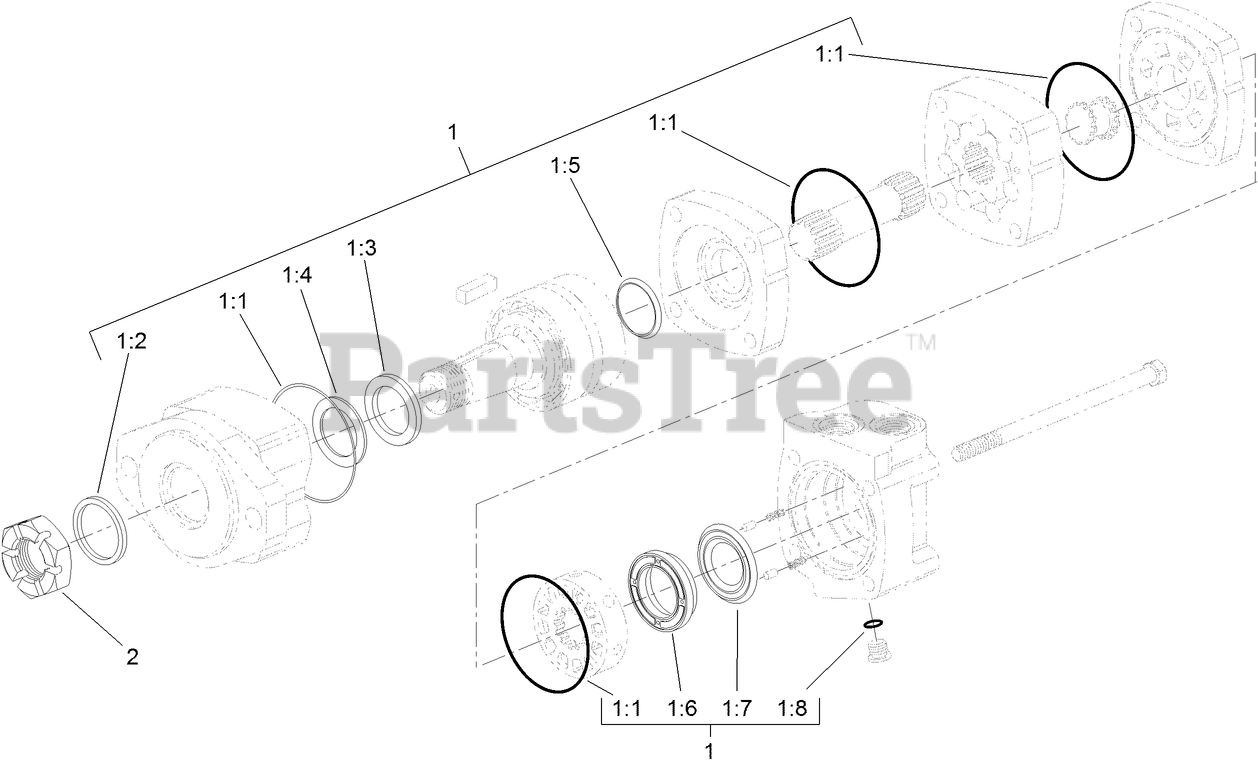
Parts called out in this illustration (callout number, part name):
1	SEAL KIT
1:1	SEAL
1:2	EXCLUSION SEAL
1:3	Outer Face Seal
1:4	Inner Face Seal
1:5	Shaft Face Seal
1:6	SHAFT SEAL
1:7	Back-Up Washer
1:8	HUB and BEARING ASM
